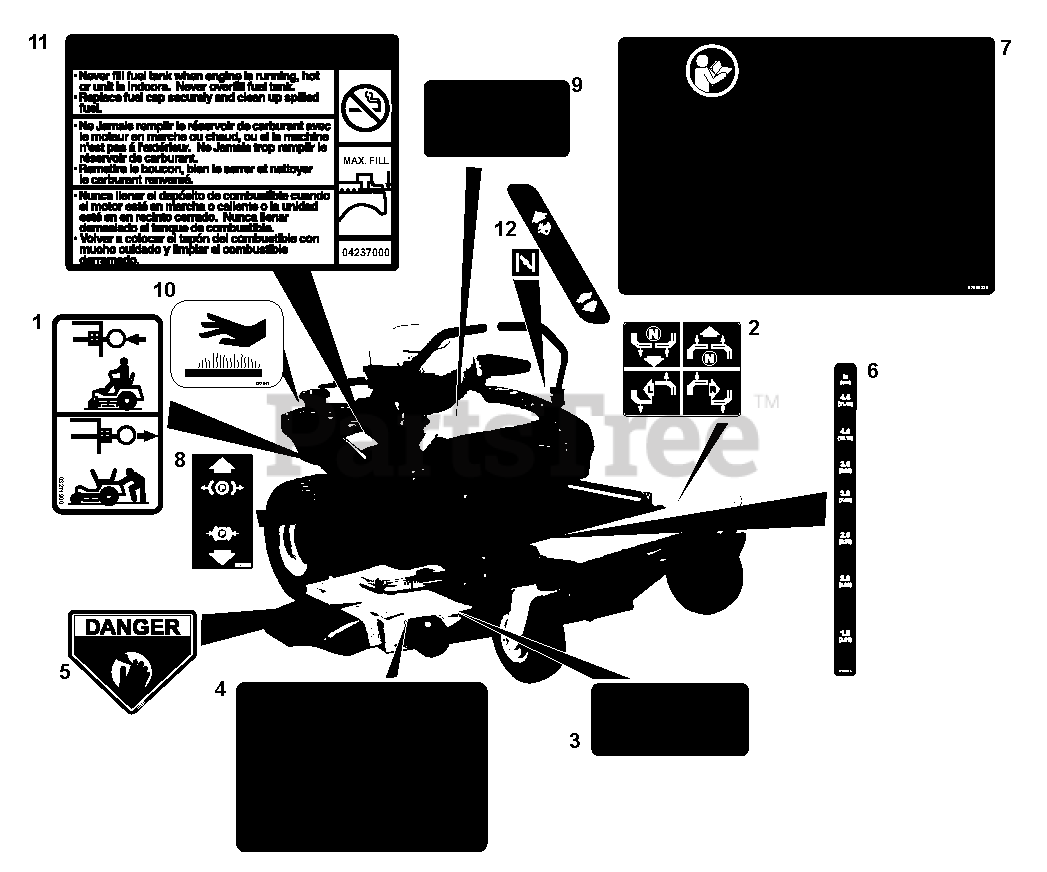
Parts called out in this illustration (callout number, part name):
1	Decal, Transmission Disconnect
2	Decal, Instructional Steering
3	Decal, Safety – Deck Guarding
4	Decal, Safety – Mower Deck
5	Decal, Danger
6	Decal, Cut Height
7	Decal, Safety – Main
8	Decal, Parking Brake Lever
9	Decal, Safety – Guarding
10	Decal, Hot Surface
11	Decal, Fuel Warning
12	Decal, Control
